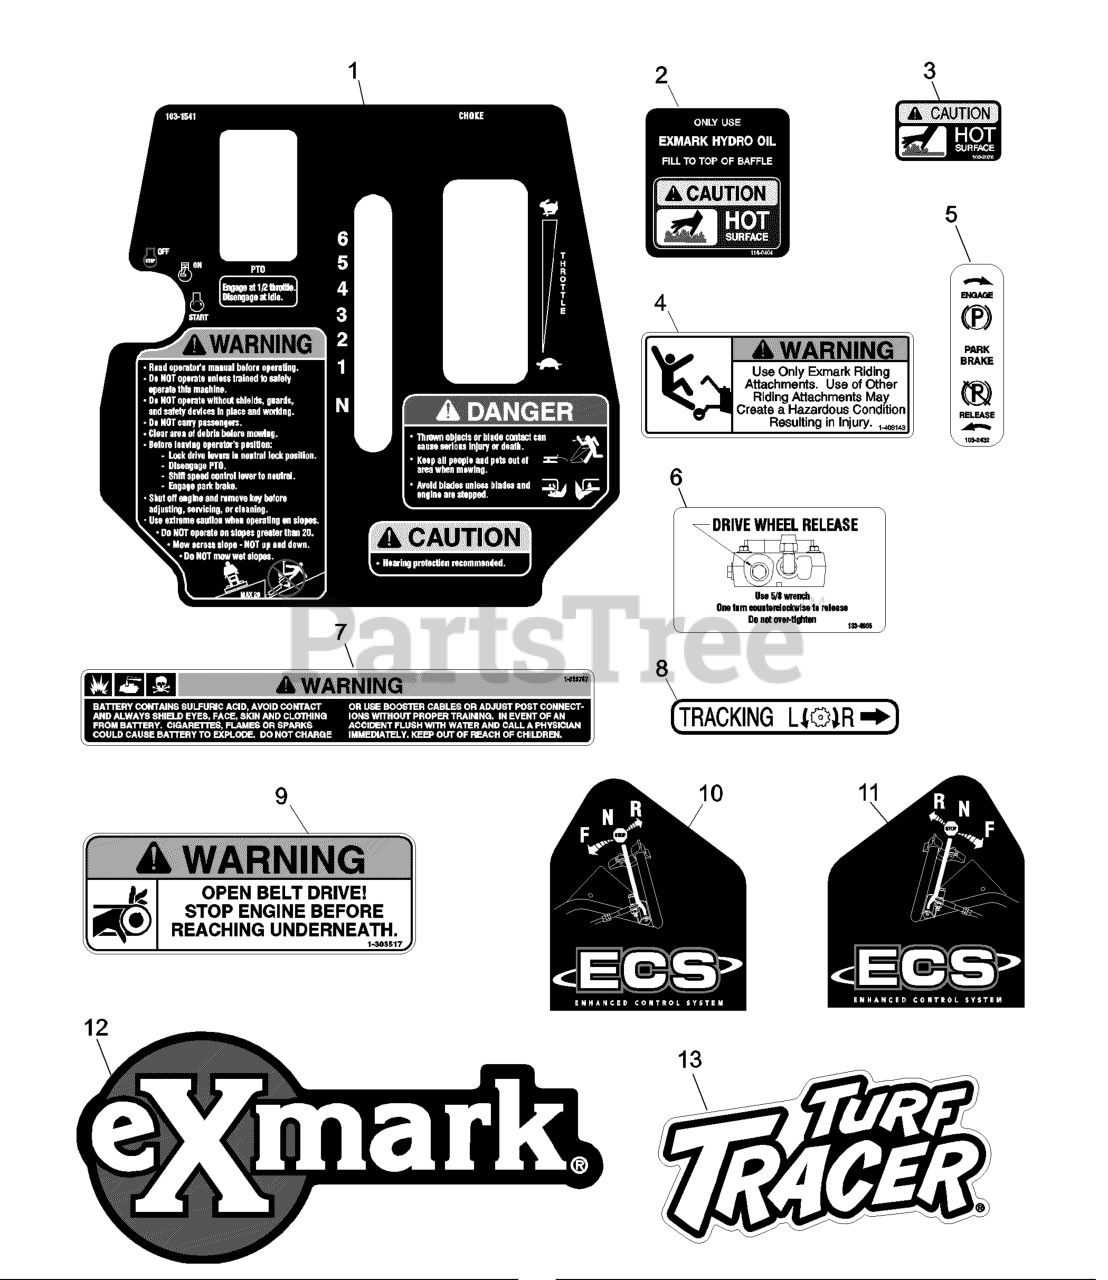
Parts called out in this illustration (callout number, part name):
1	DECAL,TTH ECS CONSOLE
2	DECAL-HYDRAULIC TANK
3	DECAL-CAUTION
4	DECAL,SULKY WARNING
5	DECAL,PARKING BRAKE
6	DECAL,DRIVE RELEASE
7	DECAL-BATTERY
8	DECAL,TRACKING ADJUST
9	DECAL,BELT DRIVE
10	DECAL,LH ECS INSTRUCTION
11	DECAL,RH ECS INSTRUCTION
12	DECAL,EXMARK LOGO
13	DECAL,TTH MODEL
